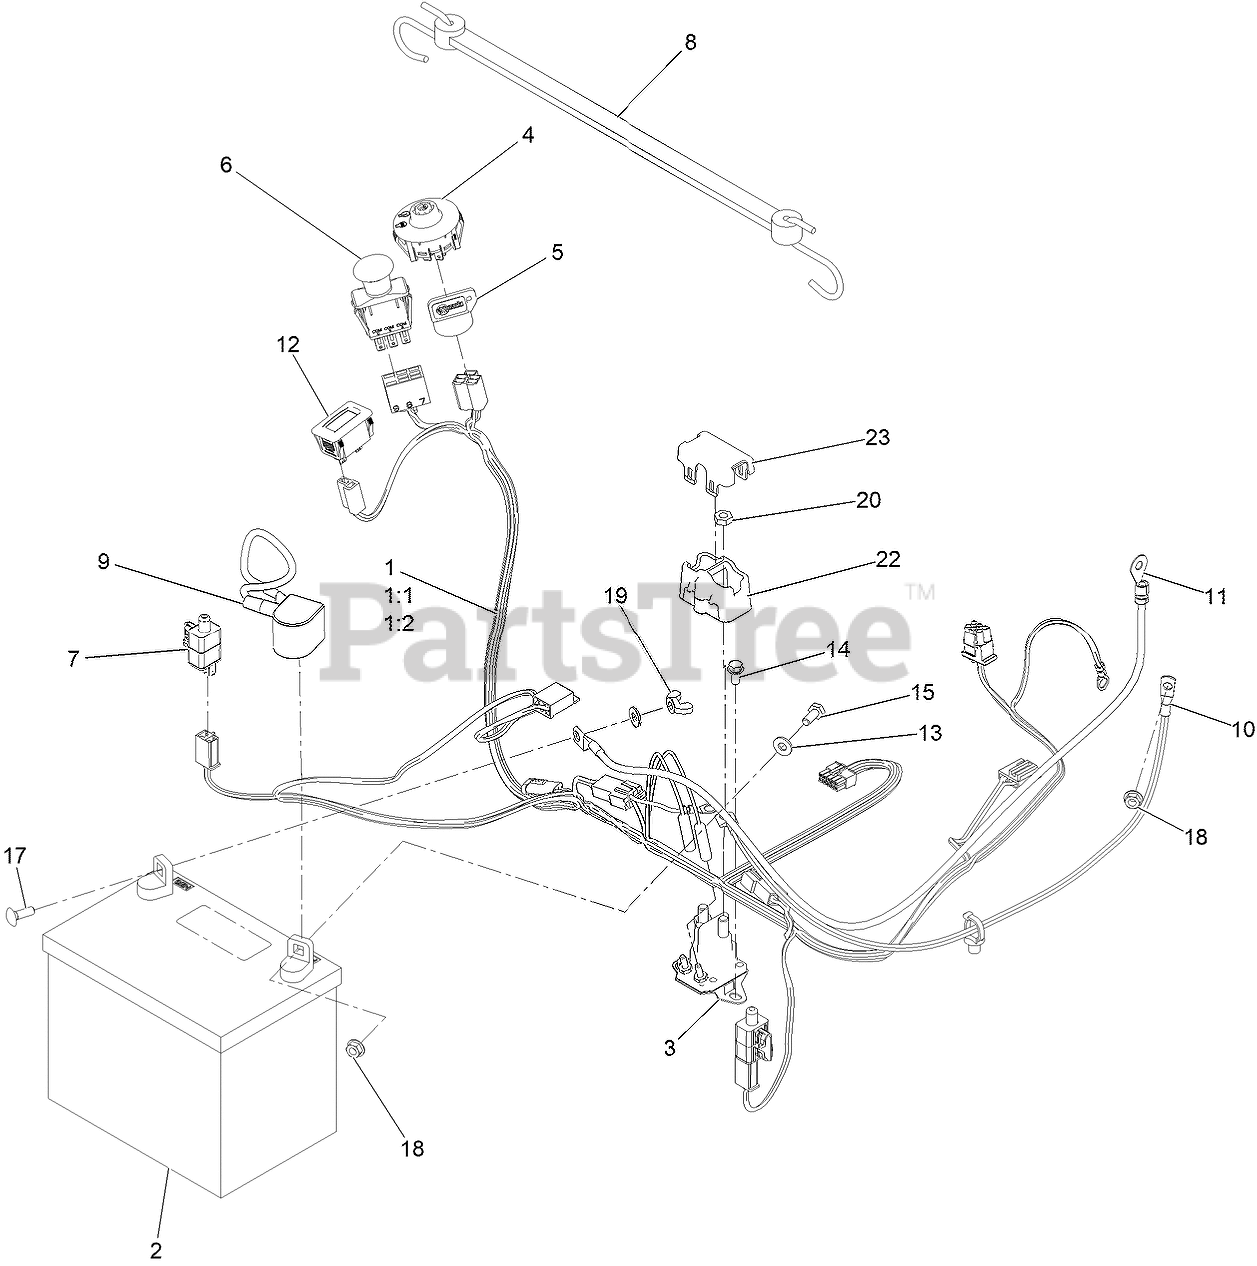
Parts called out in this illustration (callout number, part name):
1	HARNESS-WIRE
1:1	FUSE-BLADE, 15 AMP
1:2	FUSE-BLADE, 25 AMP
2	BATTERY
3	SOLENOID
4	SWITCH-IGNITION
5	KEY-IGNITION
6	SWITCH-PTO
8	STRAP-RUBBER
9	CABLE-BATTERY, POS
10	CABLE-BATTERY, RED (8 GAUGE)
11	CABLE-BATTERY, BLACK
12	HOURMETER
13	WASHER-FLAT
14	SCREW-HWH
15	SCREW-HH
17	BOLT-CARR
19	NUT-WING
20	NUT-JAM
22	COVER-SOLENOID
23	CAP-SOLENOID
